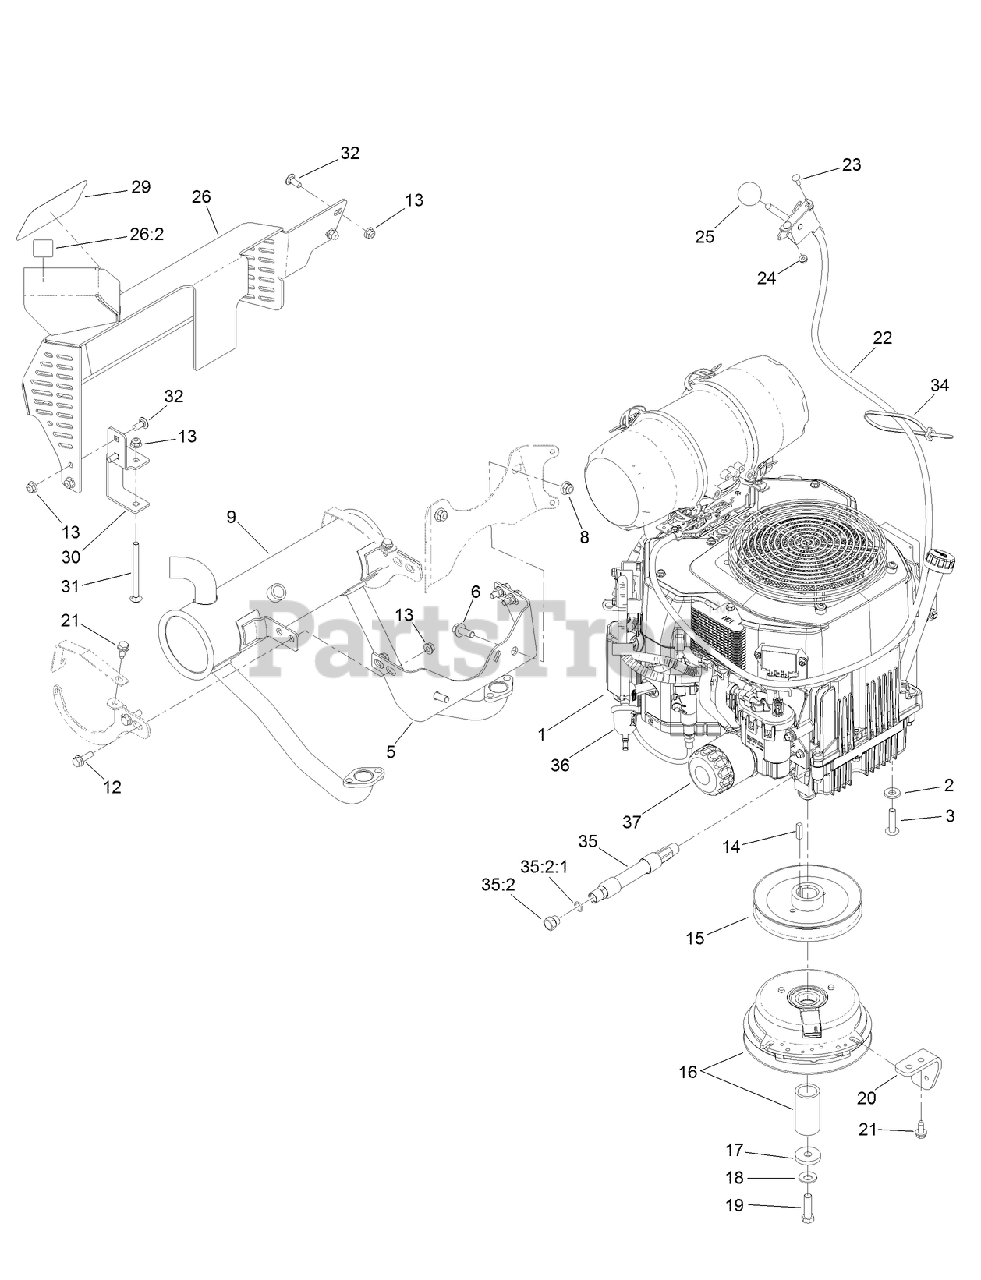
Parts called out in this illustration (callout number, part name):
1	ENGINE-KOHLER, EVC730
2	WASHER-BELLEVILLE
3	SCREW-BHTF
5	BRACKET-MUFFLER
6	SCREW-HHF
8	NUT-HF, NI
9	MUFFLER-KOHLER
12	SCREW-HHF
13	NUT-HF
15	PULLEY
16	CLUTCH
17	WASHER
18	WASHER-SPRING
20	STOP-CLUTCH
21	SCREW-HWHTF
22	THROTTLE ASM
23	BOLT-CARR
24	NUT-LOCK, FLANGE
25	KNOB-BALL
26	MUFFLER GUARD ASM
26:2	DECAL-WARNING
29	DECAL
30	BRACKET-MOUNTING, GUARD
31	SCREW-CARR
32	SCREW-CARR
34	TIE-CABLE
35	HOSE ASM
35:2	PLUG-HH
35:2:1	O-RING
36	FILTER-FUEL
37	FILTER-OIL
